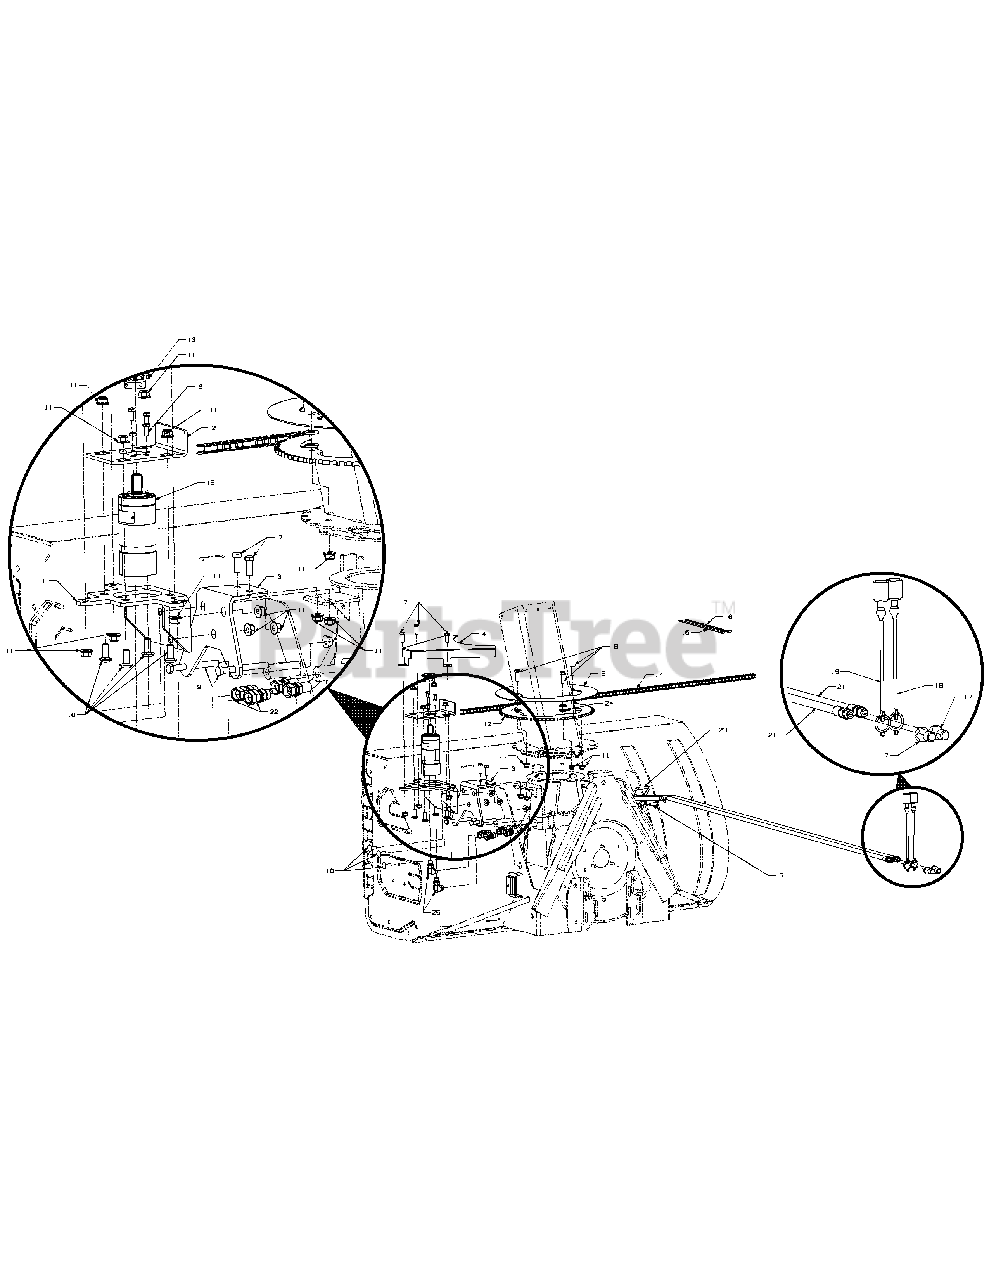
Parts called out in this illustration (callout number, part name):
1	Motor Support Bracket Ass.
2	Motor Adjustment Mount
3	Hydro Motor Support Mount
4	Chute Chain Cover
5	Hydro Rotating Sprocket Cover
6	Hex Screw, 1/4-20 x .625
7	Hex Screw, 3/8-16 x 1.00
8	Hex Screw, 3/8-16 x 1.25
9	Hex Screw, 3/8-16 x 3.50
10	Carriage Bolt, 3/8-16 x 1.0
11	Flange Lock Nut, 3/8-16
12	Chute Ring Sprocket
13	11-Tooth Sprocket
14	Roller Chain
16	Cable Tie
17	Hydraulic Coupling
21	Hydraulic Hose
22	Hydraulic Fitting
23	Hose Guide Bracket
24	Flat Washer, .406 x .875 x .105
25	Hydraulic Fitting
